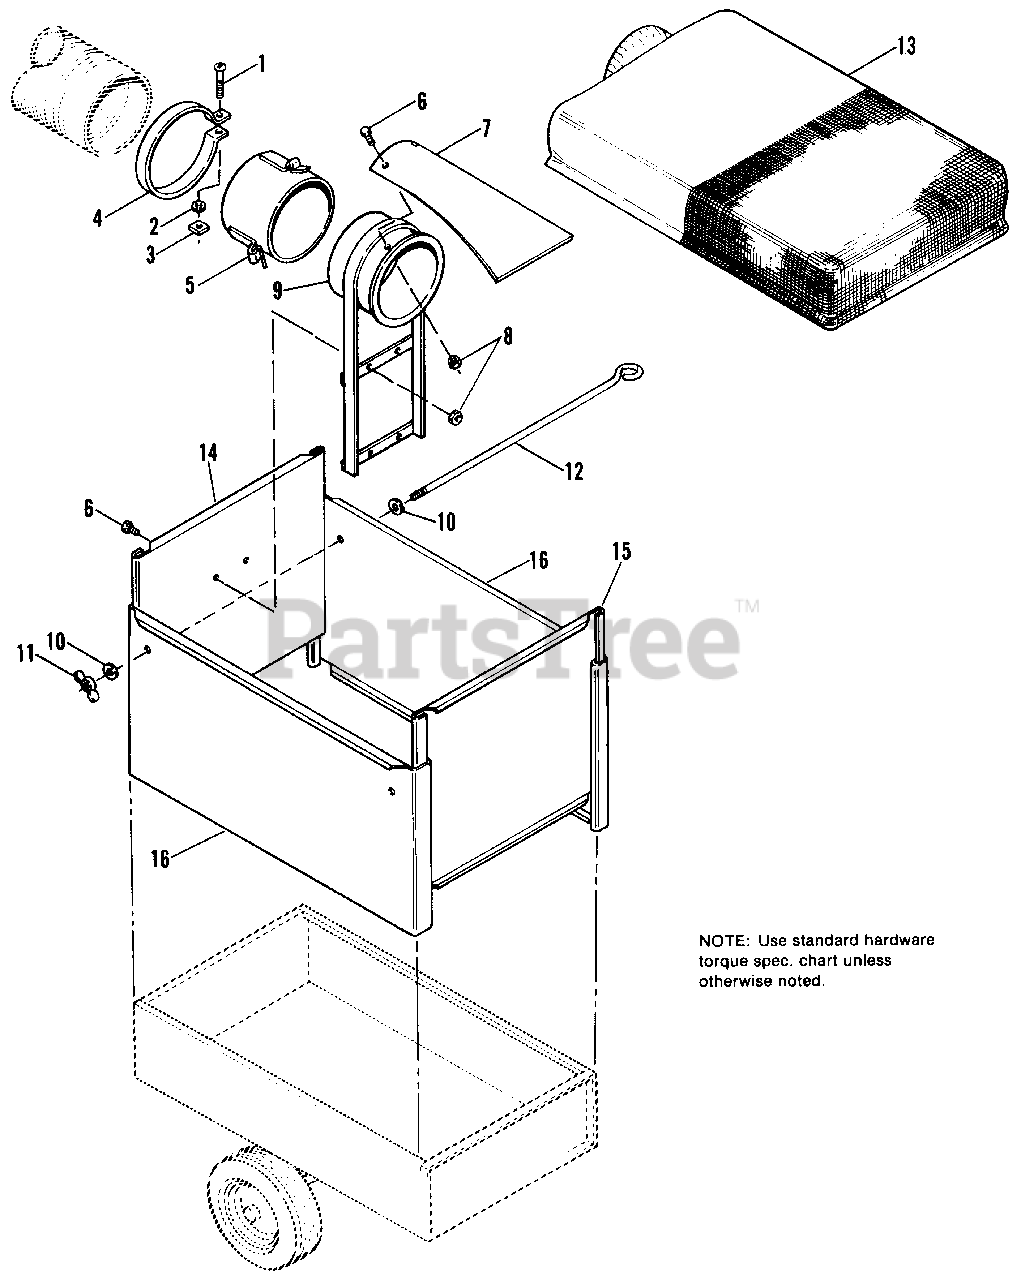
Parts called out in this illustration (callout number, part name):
1	SCREW, Rd. Hd., 1/4-20 x 3
2	LOCKWASHER, 1/4
3	NUT, Hex, 1/4-20
4	CLAMP, Hose
5	CONNECTOR, Hose, 6"
6	CAPSCREW, Hex Hd., 1/4-20 x 5/8
7	DEFLECTOR
8	LOCKNUT, Hex, 1/4-20
9	CONNECTOR, Metal, 6"
10	WASHER
11	WINGNUT, 1/4-20
14	PANEL, Front
15	PANEL, Rear
16	PANEL, Side
